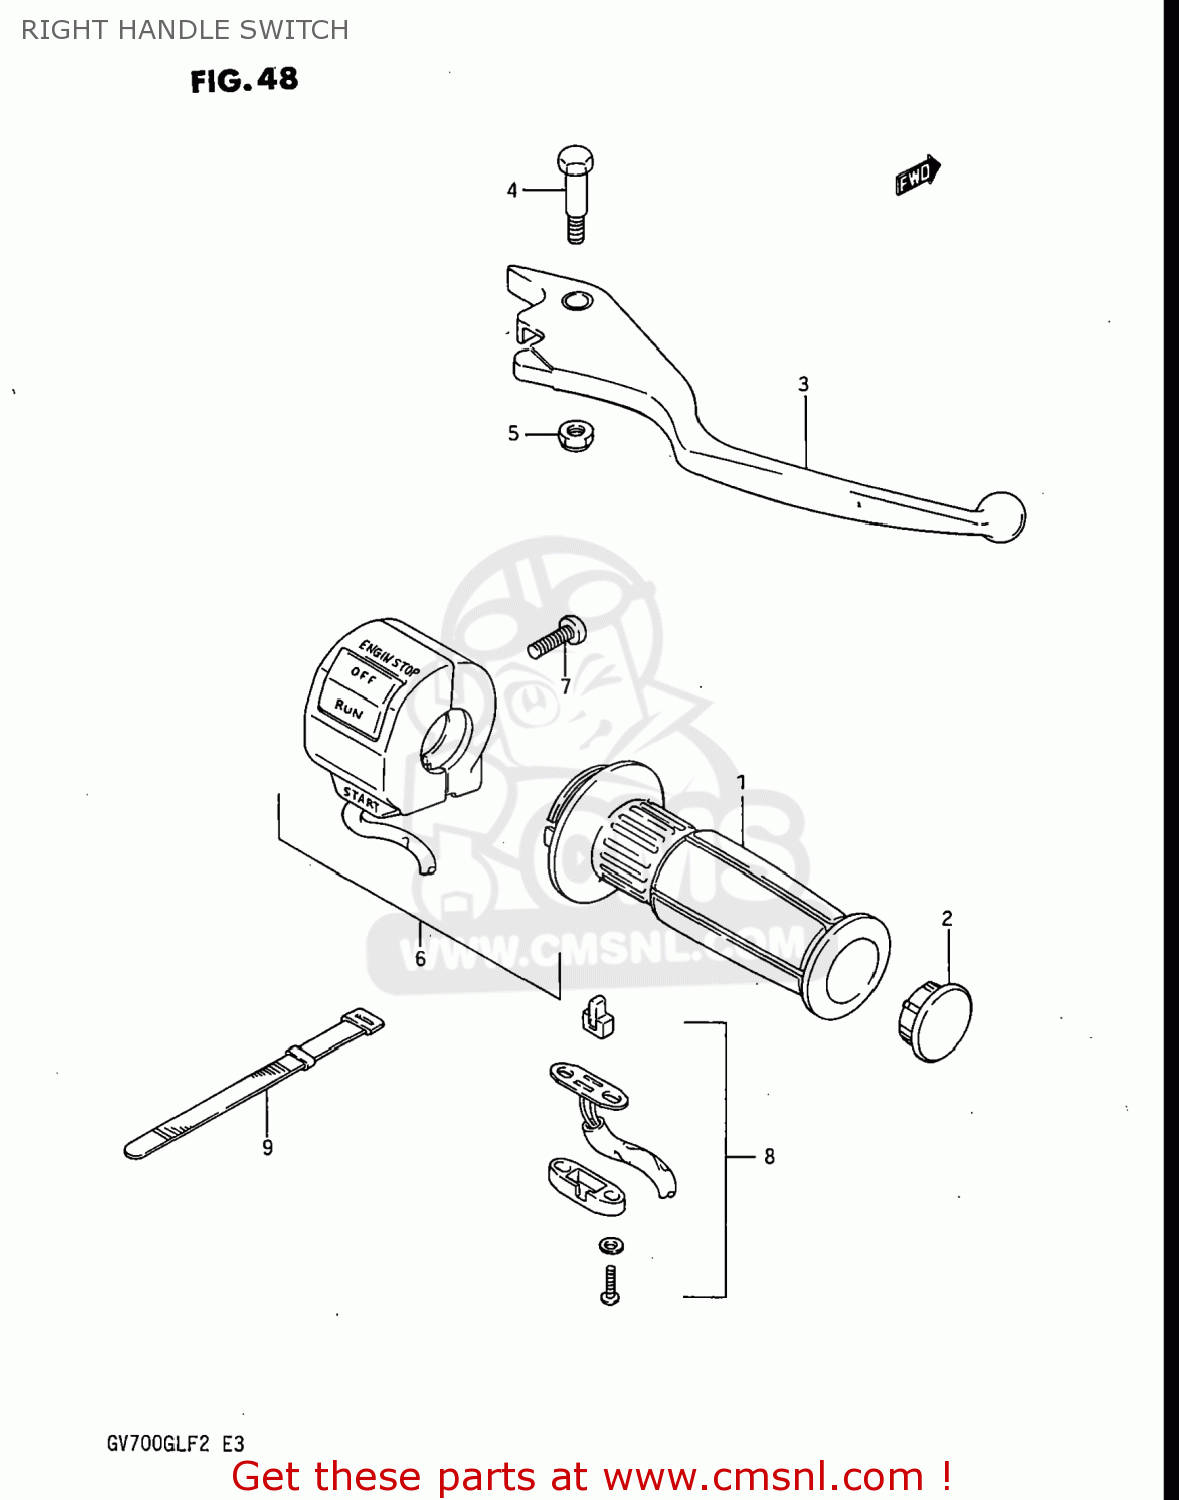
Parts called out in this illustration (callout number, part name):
1	GRIP,THROTTLE
2	CAP,GRIP END
3	LEVER,BRAKE
4	BOLT,LEVER
5	NUT
6	SWITCH ASSEMBLY,HANDLE,RIGHT
7	SCREW 5X20
8	SWITCH ASSEMBLY
9	CLAMP(L:120)
